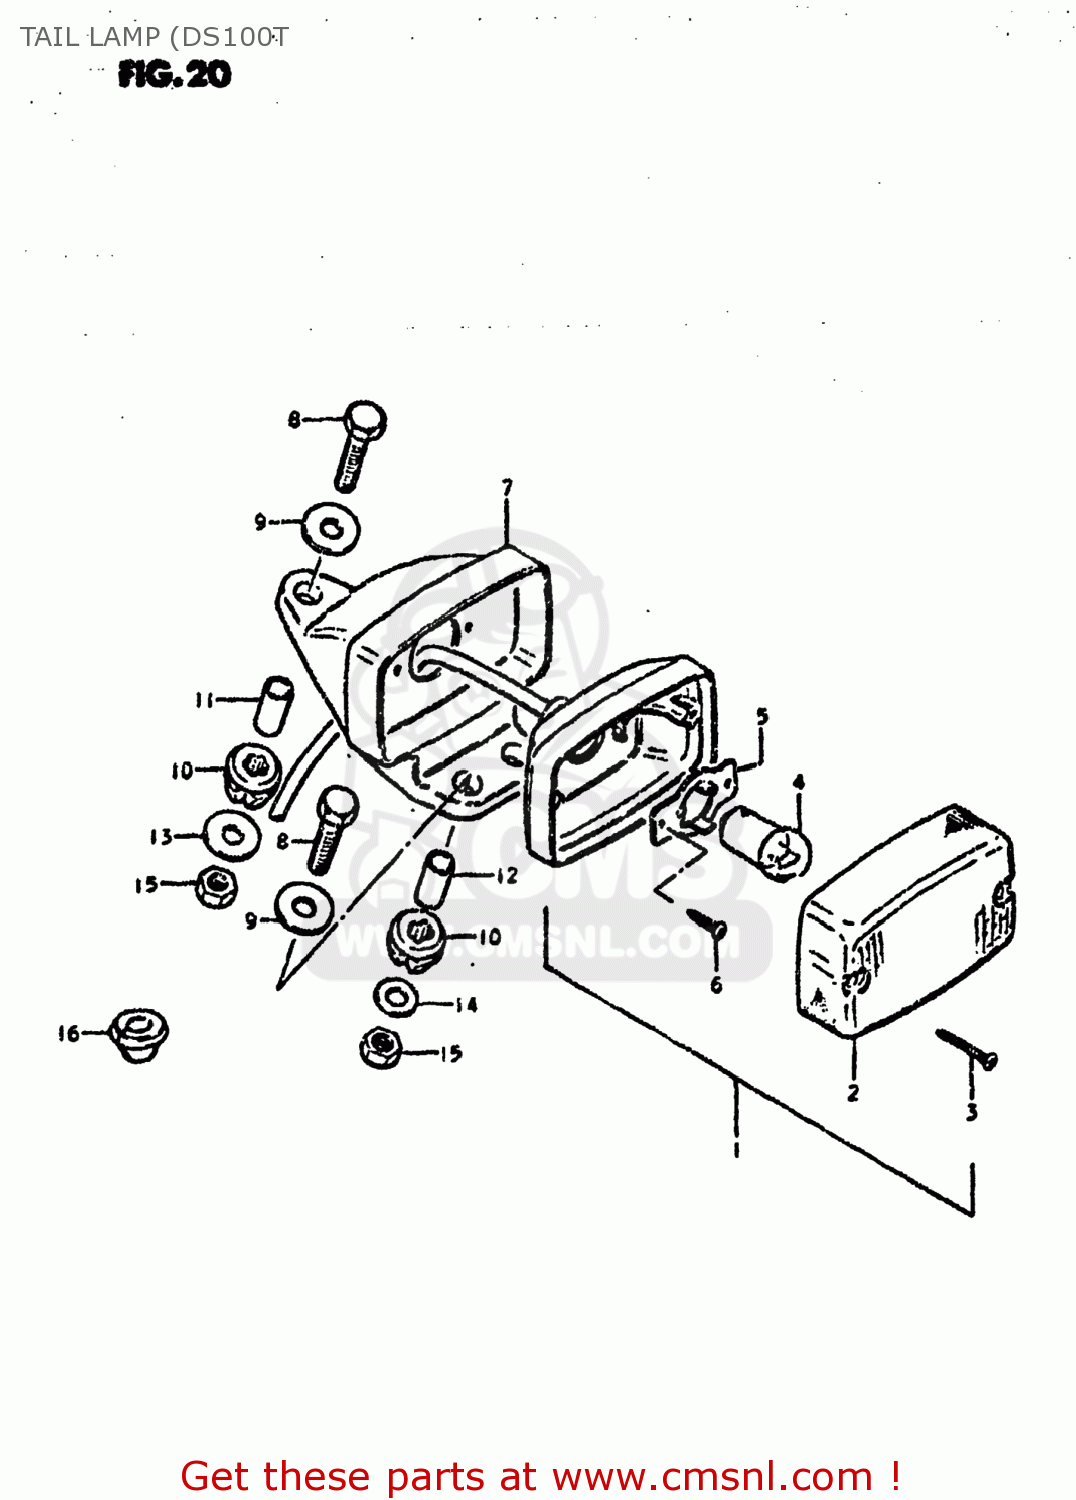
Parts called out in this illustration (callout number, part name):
1	LAMP UNIT,TAIL
2	LENS
3	SCREW
4	BULB(6V5W,TOKAI DENSO)
5	PLATE,TURN SIGNAL
6	SCREW
7	BRACKET
8	BOLT
9	WASHER (6.5X20X1.2)
10	CUSHION
11	SPACER
12	SPACER
13	WASHER
14	WASHER
15	NUT
16	GROMMET
